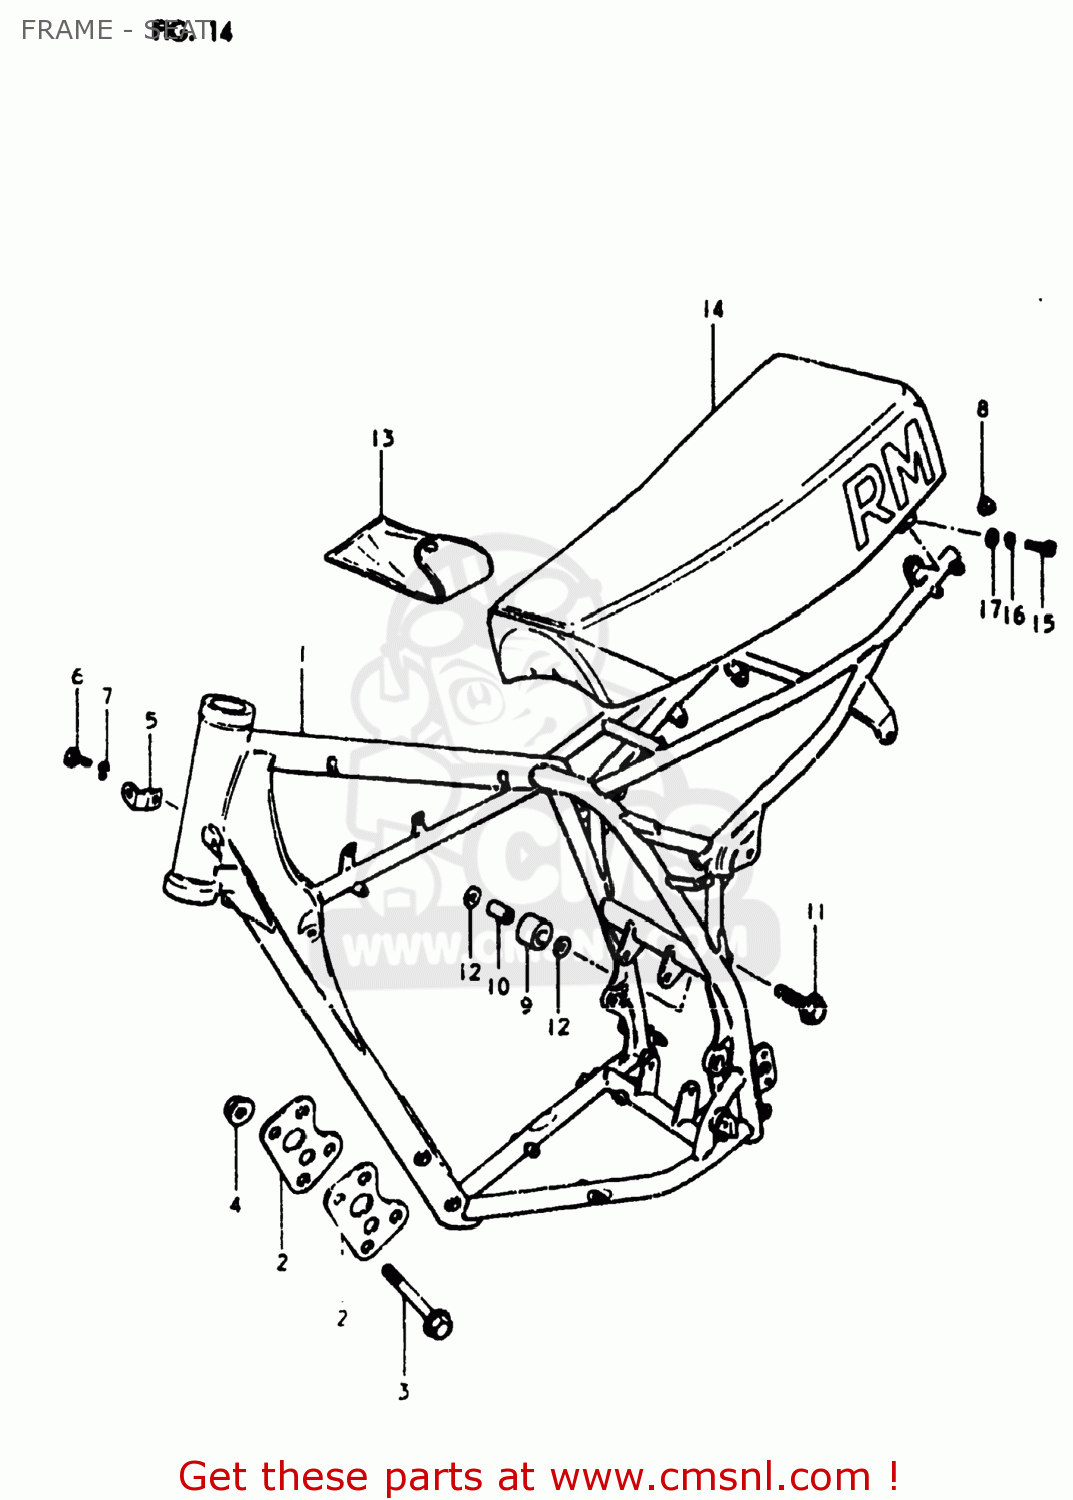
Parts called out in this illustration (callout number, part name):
1	FRAME
2	PLATE,ENGINE MOUNTING
3	BOLT(8X67)
4	NUT
5	PLATE,ENGINE MOUNTING
6	BOLT
7	LOCK WASHER
8	PLUG(OD:19)
9	ROLLER,CHAIN CONTROL
10	SPACER,CHAIN LENGTH ROLLER
11	BOLT(8X45)
12	WASHER
13	TOOL SET
14	SEAT ASSEMBLY
15	BOLT
16	LOCK WASHER
17	WASHER(6.5X18X1)
